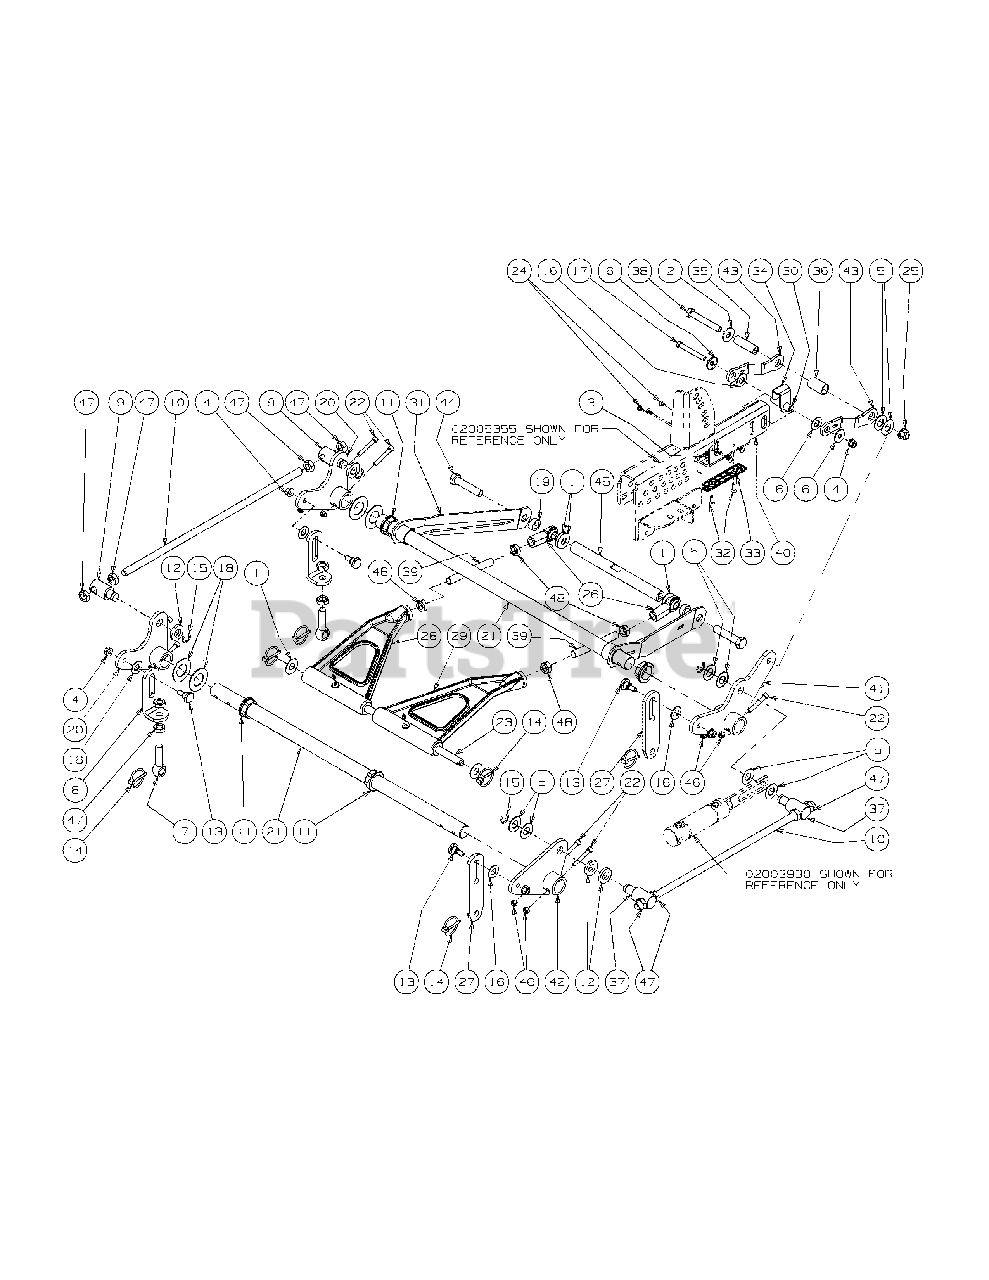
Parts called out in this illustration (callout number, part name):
1	Washer, 1.5 x .655 x .055
2	Flat Washer, 1/2
3	Lock Nut w/Nylon Insert
4	Hex Nut, Flange Lock, 3/8-16
5	Washer, .76 x 1.49 x .06
6	Flat Washer, 1.25 x .411 x .100
7	Eye Bolt, 5/8ID
8	Eye Bolt Mount Link, 5/8 ID
9	Ferule Lift
10	Lift Connector Rod
11	Hex Flange Bearing, 1.25 ID
12	Spacer, .812 ID x .268 Lg.
13	Shoulder Screw, 0.625 OD x .437 Lg.
14	Linch Pin, 3/16 Dia.
15	E Clip, 3/4 Dia.
16	Nylon Flat Washer, 5/8
17	HHCS, 3/8-16, 3.00
18	Flat Washer, 1.25 ID
19	Spacer, .630 ID x 1.06 OD x .440
20	Bellecrank Weldment Assembly
21	Deck Lift Shaft
22	Socket Head CapScrew, 5/16-18 x 2
23	Lift Link Rod
24	Rivet, 1/4 x 5/8
25	Nut, 1/2-13, FlangeLock
26	Rod End, 5/8, RH
28	Bearing Lift Brace Assembly, Left Hand includes:
29	Bearing Lift Brace Assembly, Right Hand includes:
30	Spacer, .375 ID x .625 OD x 2.20
31	Front Frame Strut Assembly
32	Flat Head Cap Screw, 1/4-20 x .75
33	Lift Wear Plate
35	Spacer, .51 ID x .75 OD x 2.38
36	Spacer, .765 ID x 1.0 OD x 1.70
37	Ferule Lift, 1.938
38	HHCS, 1/2-13 x 3.50
39	Rod, 5/8-18 x 5.50
40	Lift Tube, 3.0 x 1.5
41	Bellecrank Hydraulic Assist Assembly
42	Bellecrank Weldment Assembly
43	Offset Lift Yoke Bracket
44	HHCS, 5/8-11 x 3.00
45	Front Lift Link Shaft, Threaded
46	Nut, 5/16-18, Nylock
47	Jam Nut, 5/8-11
48	Jam Nut, 5/8-18
